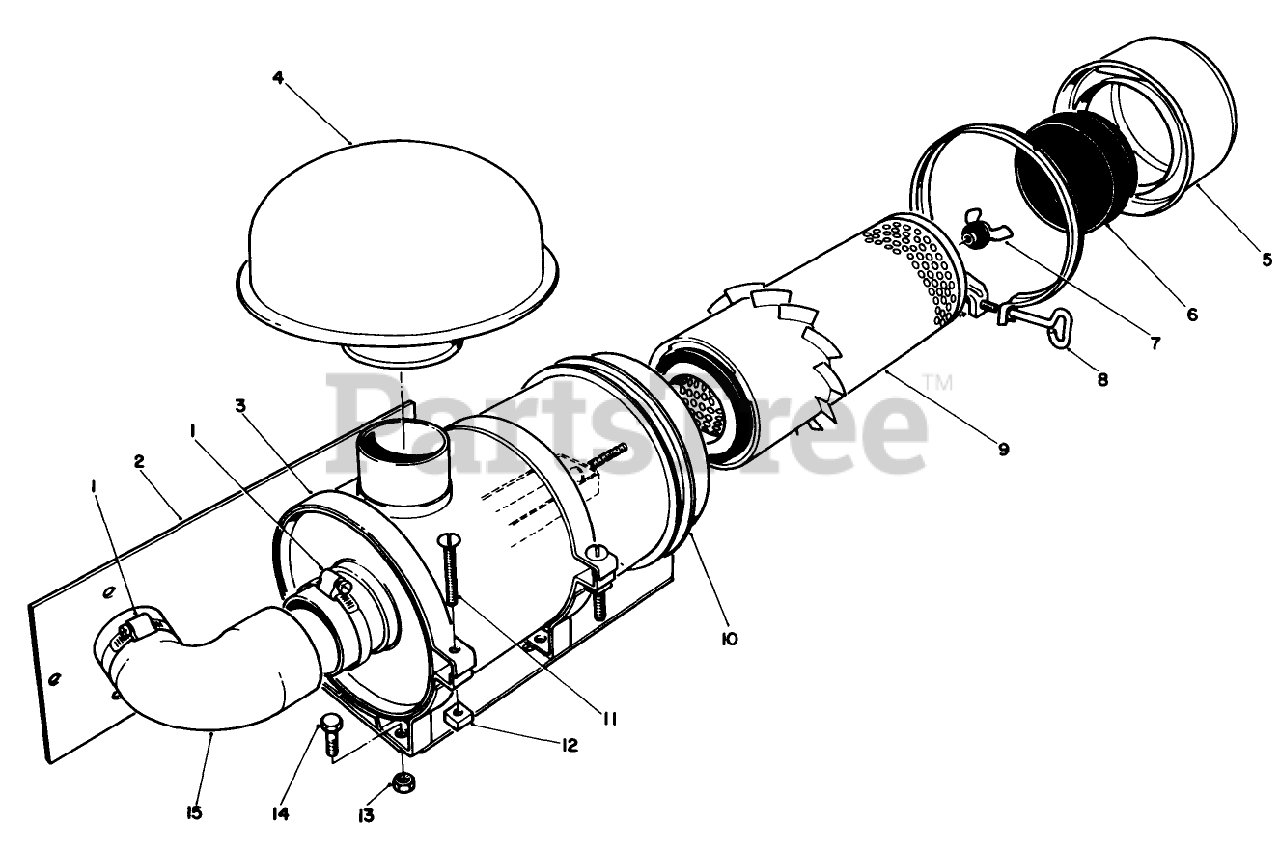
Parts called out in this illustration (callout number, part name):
1	CLAMP-HOSE
2	Bracket-Mounting-Remote Air Cleaner
3	MTG BAND ASM
4	HOOD-INLET, AIR
5	CUP ASM
6	BAFFLE
7	NUT ASM
8	CLAMP ASM
9	ELEMENT ASM
10	Body Assembly
11	SCREW
12	NUT-SQUARE
13	NUT-LOCK, NI
14	SCREW-HH
15	REMOTE AIR CLEANER HOSE
